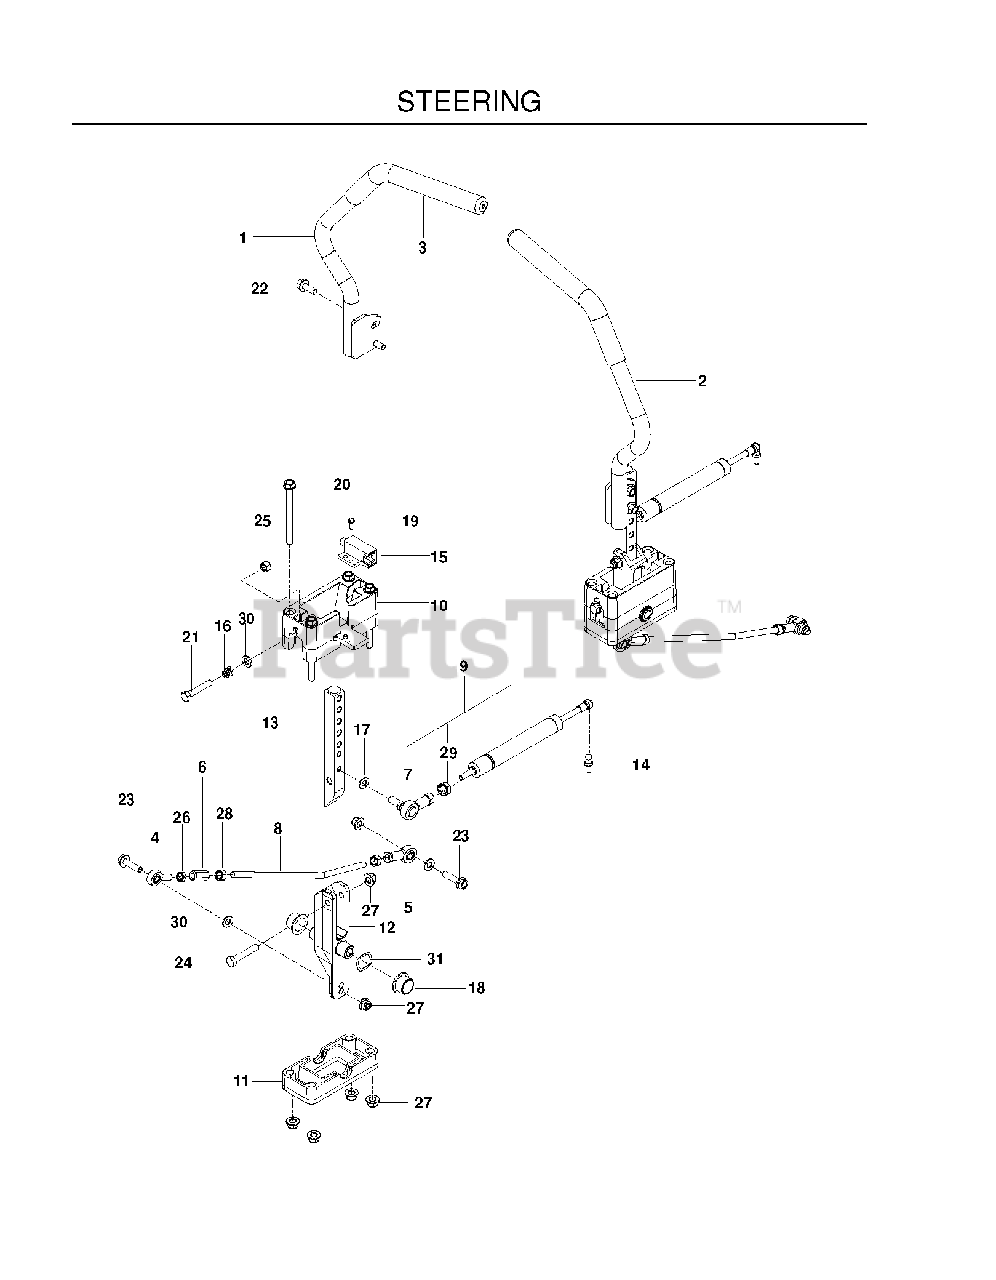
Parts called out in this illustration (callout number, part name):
1	LEVER, W/GRIP, RT
2	LEVER, W/GRIP, LT
3	GRIP - DRIVE LEVER
4	ROD END LH
5	RH ROD END
6	ROD END COUPLER
7	ROD END
8	ROD, CONTROL
9	ASSEMBLY, DAMPENER
10	BLOCK, UPPER
11	BLOCK, LOWER
12	LEVER, CONTROL
13	LEVER, MOTION
14	10MM BALL STUD
15	SWITCH, INTERLOCK
17	WASHER 5/16 LOCK
18	BEARING, FLANGE
19	SCREW #10 X 1/2 SELF TAPPING
20	HHFS 5/16-18 X 3 3/4
21	HCS 5/16-18X1-3/4 TPBLT
22	HHFS 3/8-16 X 1 GRD 5 ZD
23	HHFS 5/16-18 X 1.25 TPBLT GD 5
24	HCS 5/16C X 1 3/4
25	NUT 5/16 NYLOC
26	NUT 5/16F LEFTHAND
27	5/16-18 NYLOC FLANGE NUT
28	NUT 5/16F
29	NUT M8 X 1.25 STD HEX
30	FLAT WASHER 5/16 SAE
31	WASHER, .825 X 1.087, WAVE
